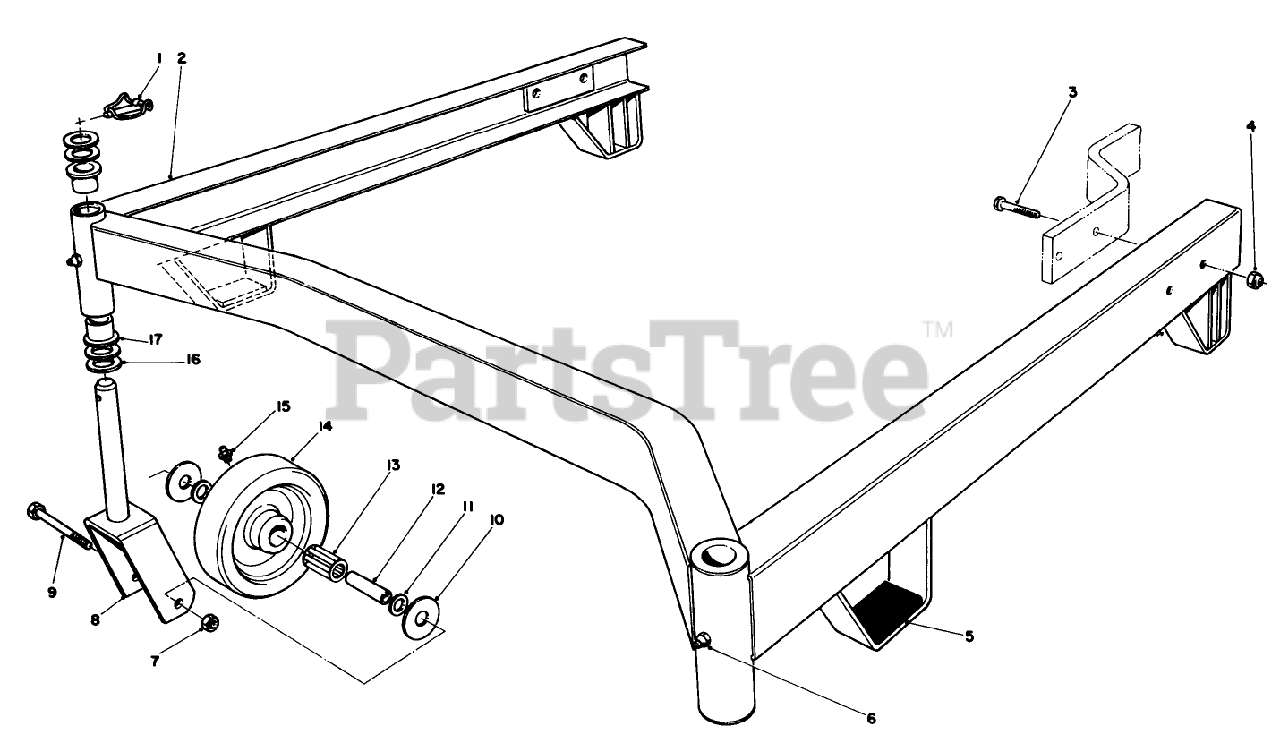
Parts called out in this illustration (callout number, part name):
1	PIN-LYNCH
2	44" Suspension Assembly (Incl. Ref. #6 & 17)
3	SCREW-HH
4	NUT-LOCK, CONE
5	Pad-Rubber
6	FITTING-GREASE
7	1/2-13 CONELOCK NUT
8	FRT CASTR FORK WA RO
9	SCREW-HH
10	WASHER
11	BEARING RETAINER
12	SPANNER BUSHING
13	ROLLER BRG
14	WHEEL
15	FITTING-GREASE
16	WASHER-THRUST
17	Bushing
